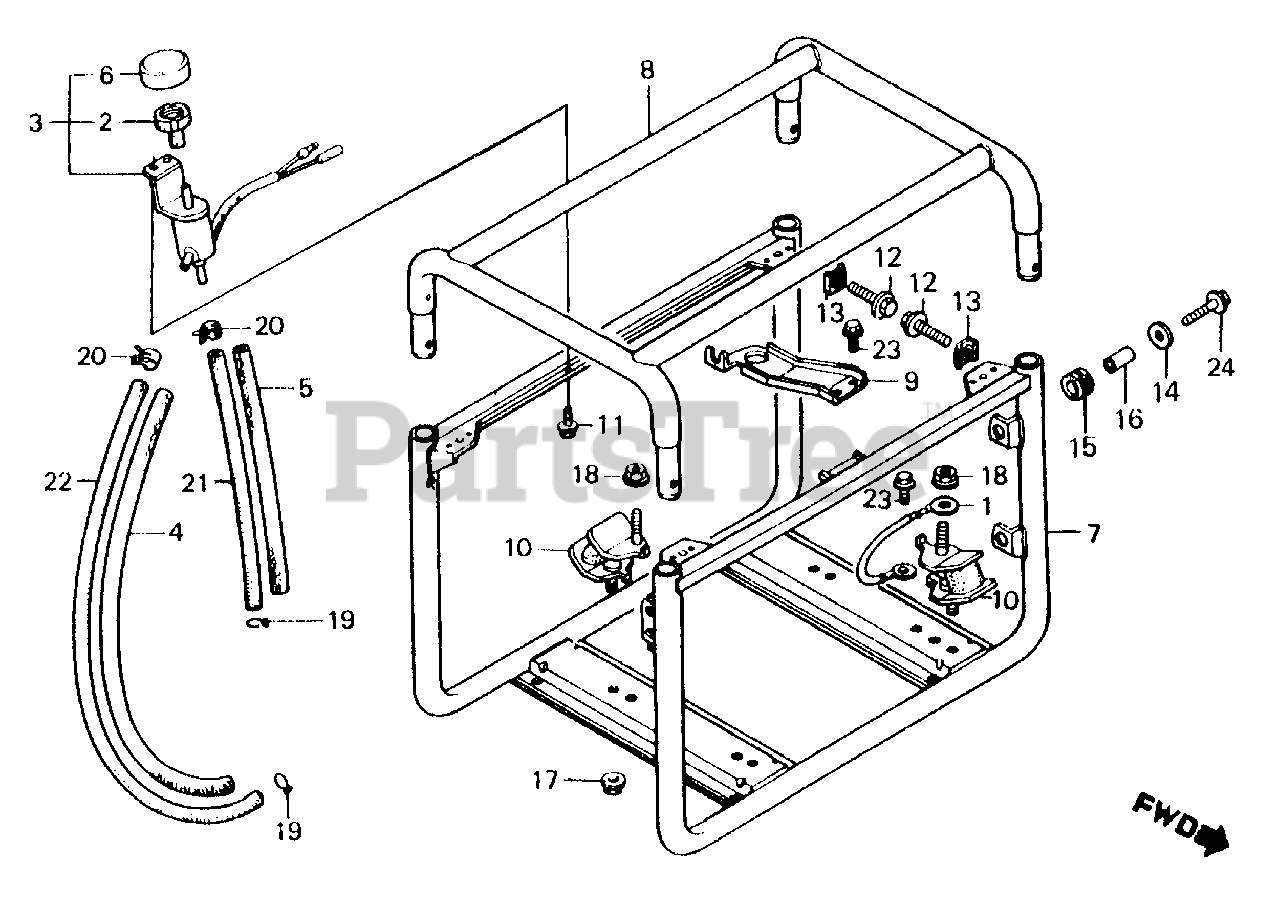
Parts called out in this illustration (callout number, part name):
1	CABLE, GROUND
2	FILTER ASSY., SOLENOID VALVE
3	VALVE ASSY., CONTROL (NOT AVAILABLE)
4	PROTECTOR, TUBE (9X390) (NOT AVAILABLE)
5	PROTECTOR, TUBE (9X130)
6	CAP, AIR FILTER
7	FRAME (LOWER)
8	FRAME (UPPER)
9	STAY, BUMP STOP
10	RUBBER (LOWER)
11	BOLT, FLANGE (5X10)
12	BOLT, FLANGE (8X20)
13	WASHER, FRAME JOINT
14	WASHER, FLAT (20MM)
15	RUBBER, CONTROL BOX
16	COLLAR, CONTROL BOX
17	NUT, FLANGE (8MM)
18	NUT, FLANGE (10MM)
19	CLIP, TUBE (B7)
20	CLIP, TUBE (D8)
21	BULK HOSE, VACUUM (3.5X1000) (3.5X140)
22	BULK HOSE, VACUUM (3.5X1000) (3.5X400)
23	BOLT, FLANGE (6X10)
24	BOLT, FLANGE (6X18)
